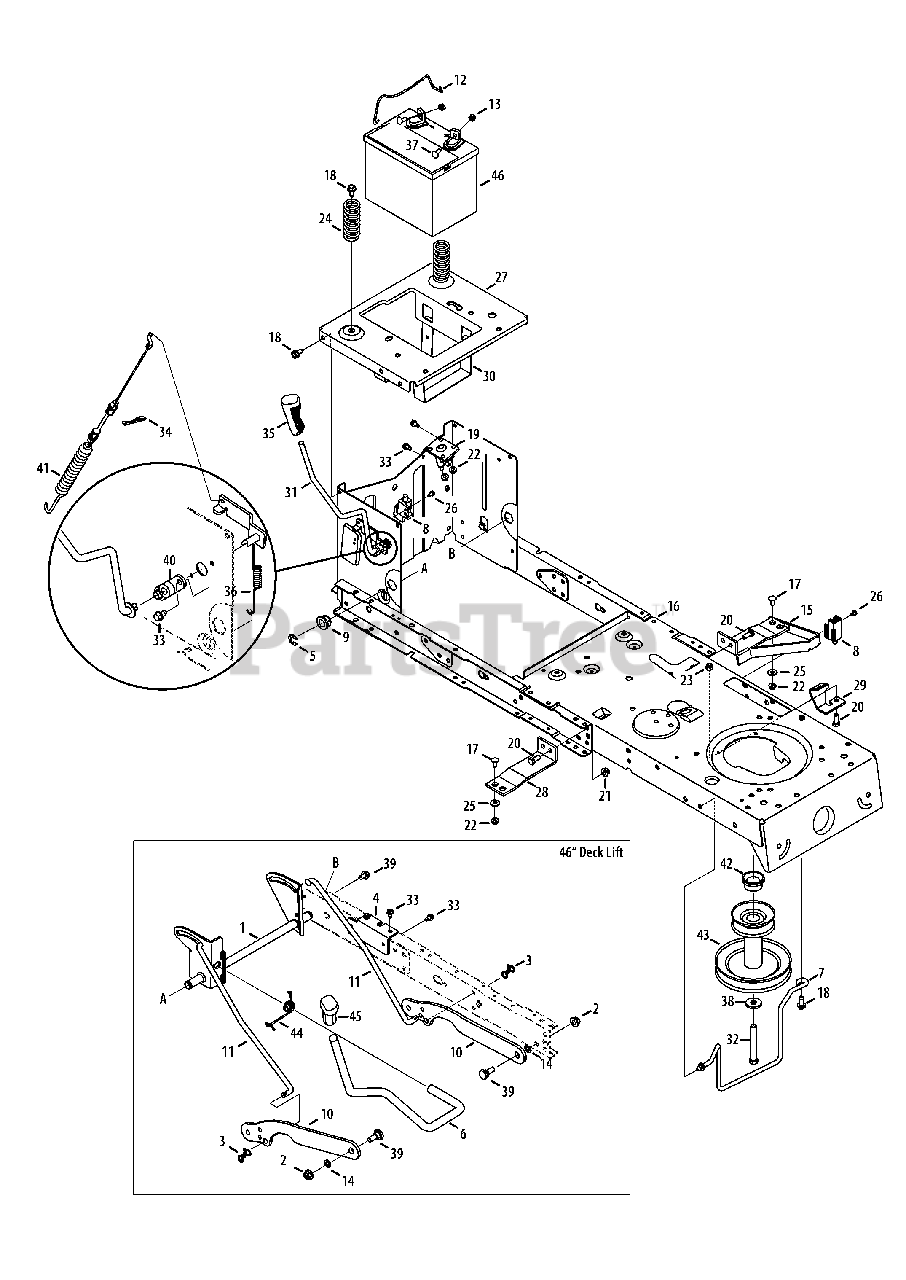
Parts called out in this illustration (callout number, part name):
1	Shaft Assembly Lift
2	Nut, Flange Lock, 3/8-16, GrF
3	Pin, Cotter, Bow Tie
4	Frame Brace Bracket
5	Ring, E-Type, .625 Dia.
6	Deck Handle, Lift, 46" Deck
7	Rod, Belt Keeper
8	Switch, Interlock
9	Bearing, Hex Flange
10	Deck Lift Link
12	Battery Hold Down Rod
13	Nut, Sems, 1/4-20
14	Washer, Flat, .385 x .62 x .063
15	Support Bracket Assembly
16	Frame Assembly
17	Carriage Screw, 1/4-20 x .62
18	Screw, 5/16-18, .750
19	Solenoid
20	Hex Screw, 5/16-18 x .75
21	Flange Lock Nut, 5/16-18
22	Nut, Flange Lock, 1/4-20, GrF
23	Hex Lock Nut, 5/16-18
24	Spring, Compr. , 1.28 OD x 3.125
25	Flat Washer, .28 x .74 x .063
26	Shoulder Screw, #10-32 x .500
27	Seat Bracket, Frame
28	Bracket, Runing Board
29	Frame Support Bracket
30	Bracket, Battery
31	Handle Assembly, PTO
32	Hex Screw, 7/16-20 x 3.25
33	Screw, 1/4-20, 0.500
34	Pin, Click, .092 x 1.64
35	Grip, Handle, 3/8
36	Spring, Extension
37	Screw, Carriage, 1/4-20, .75, Gr5
38	Washer, Flat, .450 x 1.250 x .164
39	Bolt, Shldr. .500 x .270 3/8-16
40	Bearing, PTO
41	Cable, Deck Engagement
42	Spacer, 1.010 x 1.400 x .825
43	Engine Pulley
44	Spring, Torsion 46" Deck
45	Grip, Handle, 5/8
46	Battery, 155 CCA
